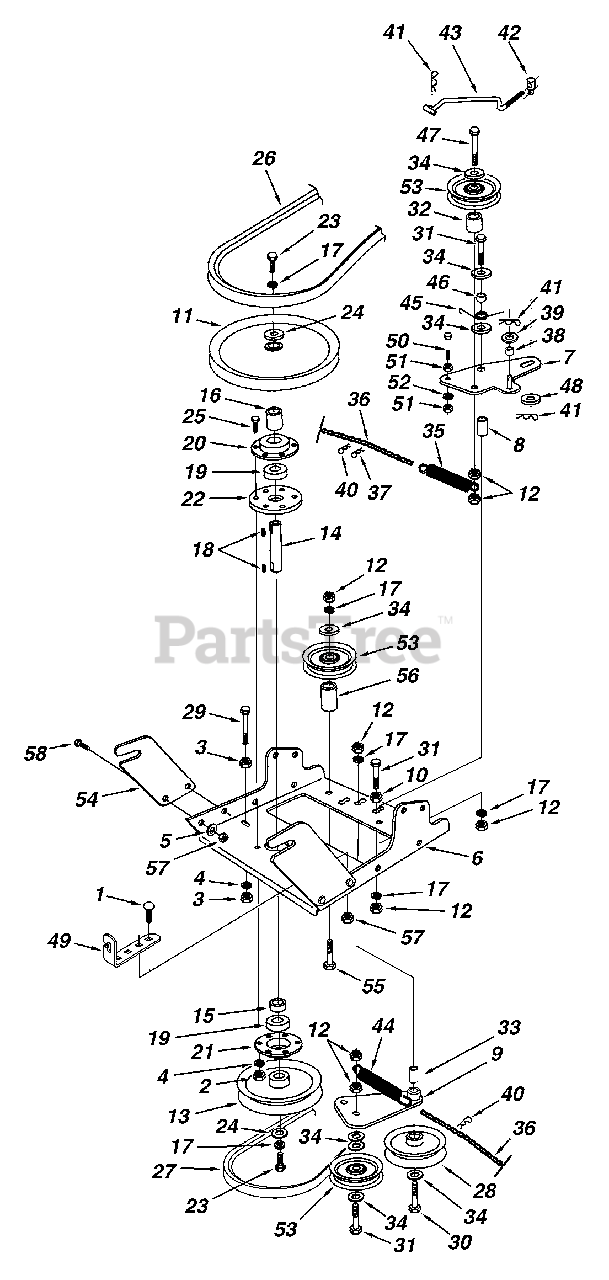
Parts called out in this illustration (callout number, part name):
1	Carriage Bolt, 5/16-18 x 3/4"
2	Hex Lock Nut, 5/16-18
3	Hex Nut, 5/16-18
4	Lock Washer, 5/16"
5	Washer, 5/16" Std. Wrt.
6	Frame, Clutch and Pulley
7	Idler Arm Assembly
8	Spacer, Pivot
9	Idler Bracket Assembly
10	Hex Nut, 3/8-16
11	Pulley, V Type 9"
12	Nut, Hex Lock, 3/8-16
13	Pulley, V Type 5-1/2"
17	Lock Washer, 3/8"
19	Bearing, Ball
20	Housing, Bearing
21	Housing, Open Bearing
22	Spacer, Spindle
23	Hex Bolt, 3/8-24 x 1"
25	Hex Bolt, 5/16-18 x 1"
26	Belt, V Type Drive (55")
26	Belt, V Type Drive (56")
27	Belt, V Type Auger
28	Pulley, V Type 4"
29	Hex Bolt, 5/16-18 x 3-1/2"
30	Hex Bolt, 3/8-16 x 2-1/2"
31	Hex Bolt, 3/8-16 x 2"
33	Spacer, Pivot
34	Washer, 3/8"
37	Pin, Hair Cotter, 3/32"
39	Washer, 1/4"
40	Pin, Hair Cotter #4 (1/8")
41	Pin, Hair Cotter 5/64"
43	Rod, Engagement
45	Spring, Torsion
47	Hex Bolt, 3/8-16 x 2-3/4" Lg.
48	Washer, Flat 3/8"
49	Cable Bracket
50	Hex Bolt, 1/4-20 x 2-1/2"
51	Hex Nut, 1/4-20
52	Lock Washer, 1/4"
53	Pulley, Flat 3-5/8"
54	Rear Pulley Frame Bracket
55	Hex Bolt, 3/8-16 x 3-1/4"
57	Hex Nut, 5/16-18 Nylock
58	Hex Bolt, 5/16-18 x 3/4"
